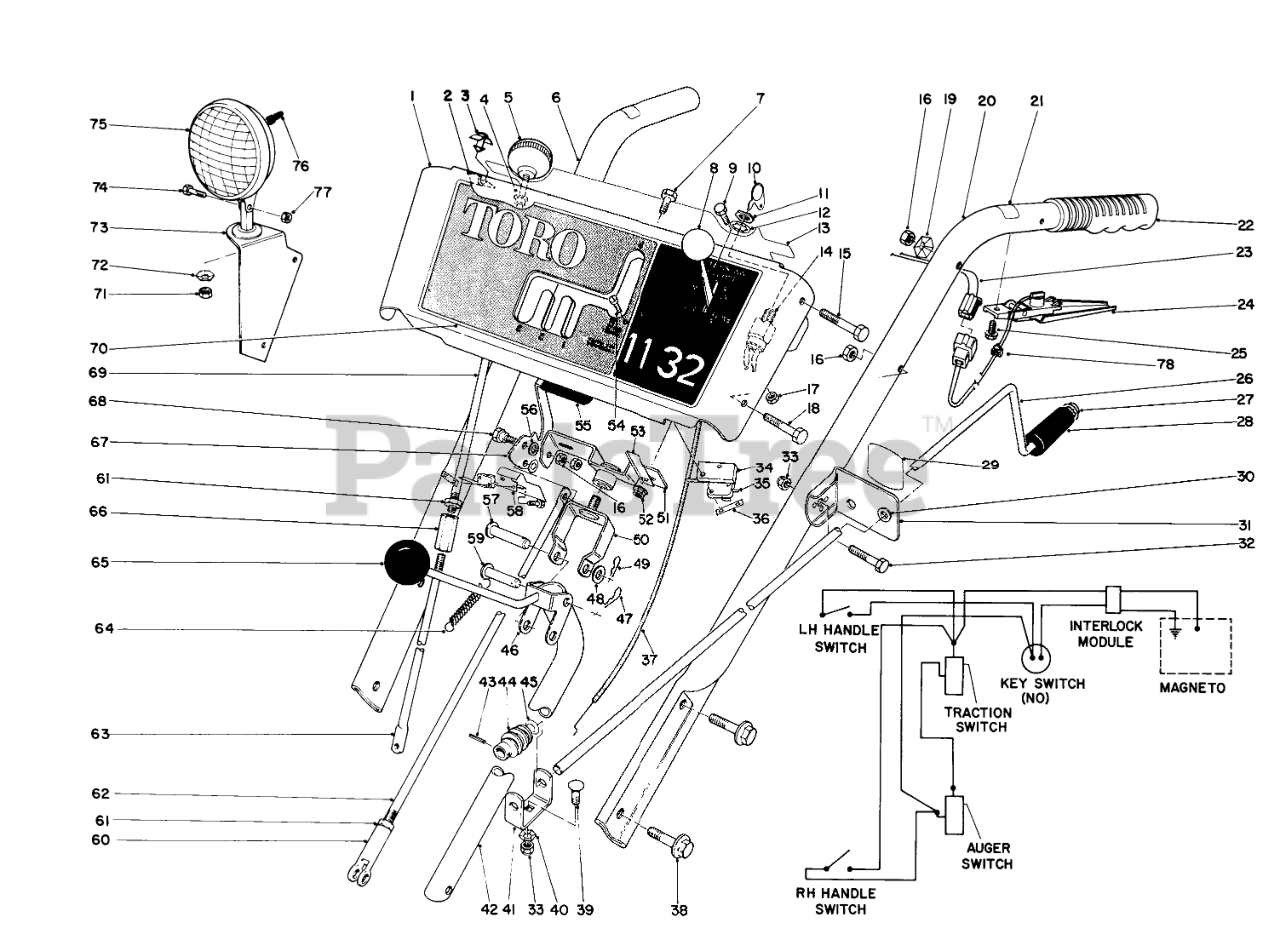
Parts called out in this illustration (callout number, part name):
1	Escutcheon Plate (Incl. Ref. #13 & 70)
2	WIRE CLAMP
3	Mounting Stud
4	NYLINER #6LI-FF TYPE 7
5	KNOB-LEVER
6	Handle Right
7	SCREW-HH
8	CONTROL KNOB
9	HEX HEAD SEMS 10-24X1/2
10	Key
11	NUT-HH
12	WASHER-TOOTH, INTERNAL
13	BACK ESCUTCH DECAL
14	Key Switch (Incl. Ref. #11 & 12)
15	SCREW-HH
17	NUT-LOCK, NI
18	SCREW-HH
19	Washer
20	HANDLE LEFT
21	INTERLOCK DECAL
22	Grip Handle
23	Wire Harness (Incl Ref. #78)
24	INTERLOCK HDLE SWITCH
25	SCREW
26	Chute Control Rod
27	RETAINER-PUSH ON
28	GRIP-CONTROL, CHUTE
29	CHUTE DECAL
30	Bushing
31	Bracket-Chute Control Mtg. (Incl. Ref. #29 & 30)
32	SCREW-HH
33	NUT-LOCK, NI
34	SWITCH MTG PAD
35	SWITCH-MICRO
36	NUT-SPEED
37	Throttle Contrl
38	SCREW-HHF
39	BOLT-CARR
40	WASHER-LOCK
41	WORM BRACKET
42	Rod Traction Shift
43	PIN-SPRING
44	GEAR-WORM, CHUTE
45	WASHER-SPRING
46	SHIFT ROD WA
47	PIN-COTTER
48	WASHER-FLAT
49	PIN-HAIR
50	PIVOT BRKT WA
51	SWIVEL BLOCK WA
52	NUT-LOCK, HHF
53	Retainer Wire
54	SCREW-SPH
55	AUGER CLUTCH HND GRIP
56	WASHER-PLAIN
57	PIN-CLEVIS
58	SWITCH BRKT
59	PIN-CLEVIS
60	CLEVIS
61	NUT-HJ
62	DRAG LINK
63	LOWER WHL CLUTCH ROD
64	CONT ROD SPRING 0
66	WHL ROD COUPLING
67	Auger Clutch Handle
68	SCREW-SHOULDER
69	UP WHEEL CLUTCH ROD
70	ESCUTCHEON DECAL
71	NUT-HEX
72	LOCKWASHER-PYRAMID
73	Lamp Mount
74	SCREW-HH
75	HEADLAMP ASM
76	BOOT-SWITCH
77	NUT-HEX, SIDE DEFORM
78	Mount-Wire
